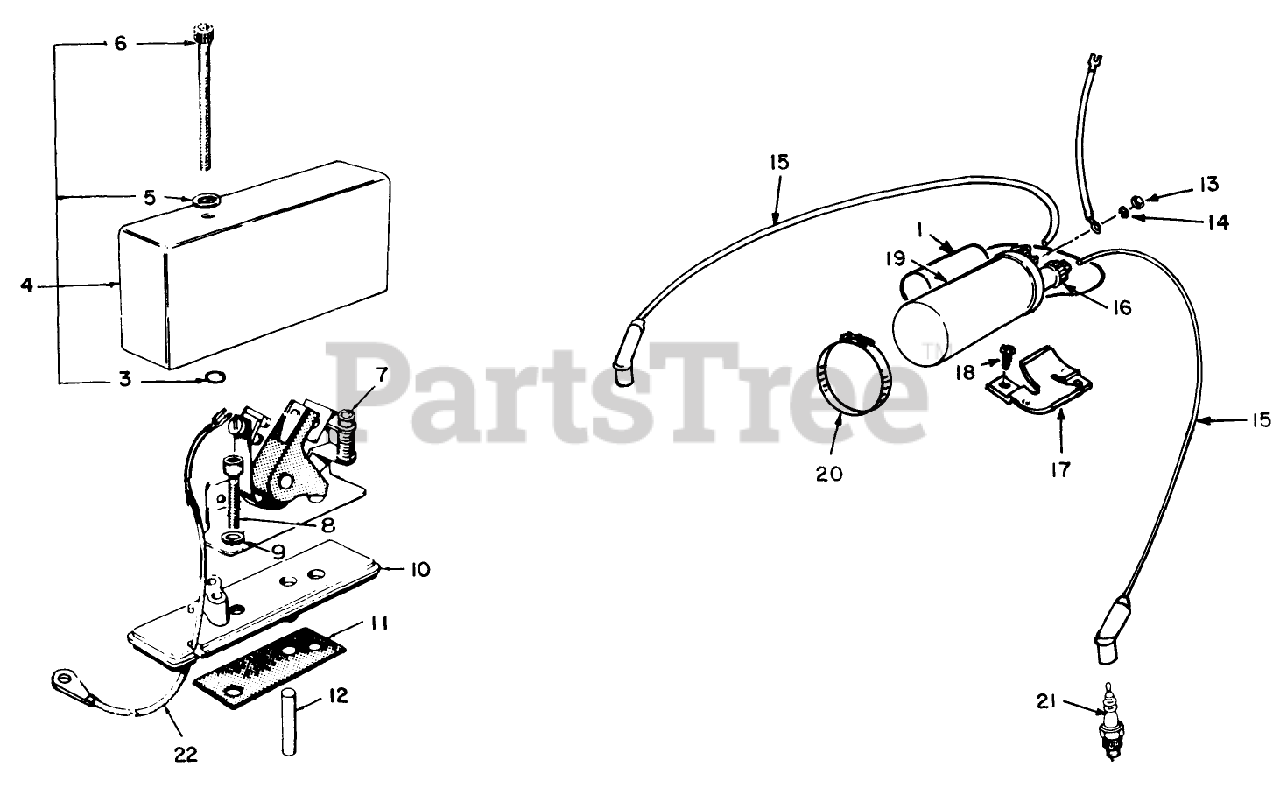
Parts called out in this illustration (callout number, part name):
1	CONDENSER
3	Retainer ("0" Ring)
4	BREAKER BOX COVER
5	FLAT WASHER
6	SCREW-HSH
7	BREAKER ASM
8	Cap Screw Socket Hd.
9	WASHER-LOCK
10	BREAKER BASE
11	GASKET
12	PLUNGER
13	Nut-Hex, Special
14	M5 SPRING WASHER
15	CABLE KIT
17	BRACKET
18	HX WSHR HD CAPSCREW
20	Clamp, Ignition Coil
21	SPARK PLUG
22	Lead-Breaker Box to Coil
